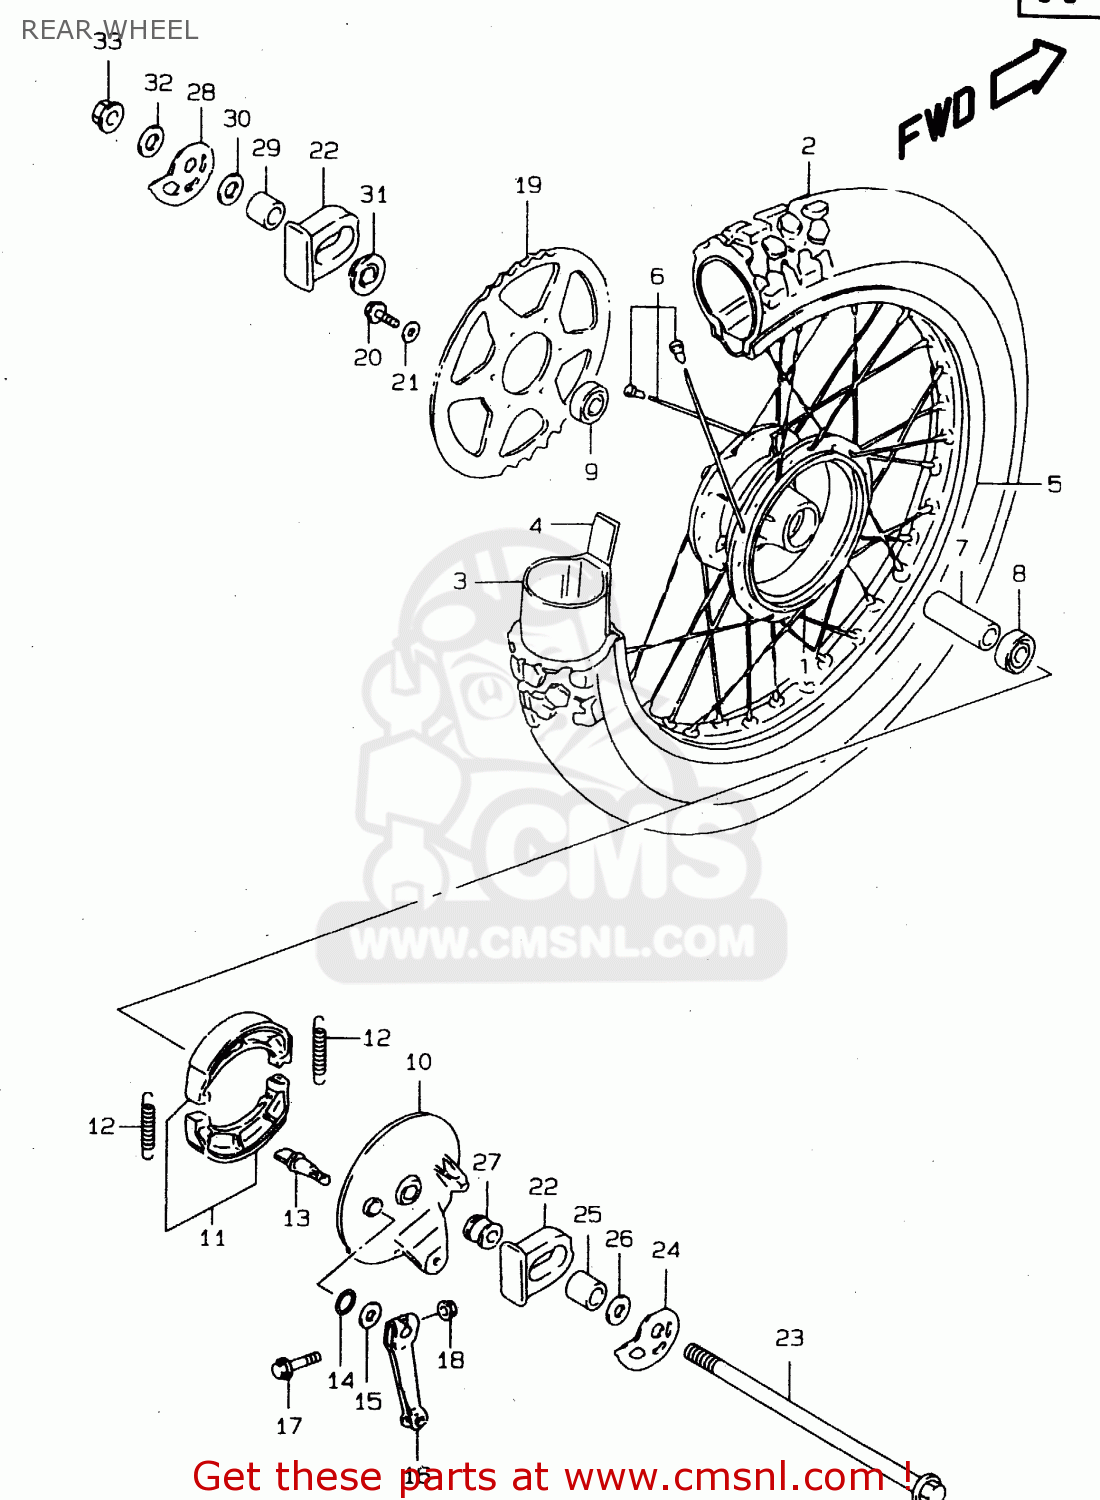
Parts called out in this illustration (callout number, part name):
1	HUB,RR WHEEL
2	TIRE,RR(90/90-18 51P)
3	TUBE ASSY,INNER
4	PROTECTOR,INNER TUBE
5	RIM,RR WHEEL(18X1.85 FE)
6	SPOKE SET,RR WHEEL
7	SPACER(15.3X21.7X107.5)
8	BEARING
9	BEARING
10	PANEL,RR BRAKE ANCHOR
11	SHOE SET,BRAKE (NAS)
12	SPRING(L:34)
13	CAM,BRAKE
14	O RING(D:2.5,ID:13.8)
15	WASHER(14.5X22X1.6)
16	LEVER,RR BRAKE CAM
17	BOLT
18	NUT
19	SPROCKET,RR(NT:53)
20	BOLT(8X30)
21	WASHER
22	CAP,RR SWINGING ARM
23	AXLE,RR
24	ADJUSTER,CHAIN,R
25	SPACER,CHAIN ADJUSTER
26	WASHER(15.5X26X2.3)
27	SPACER,RR AXLE,R
28	ADJUSTER,CHAIN,L
29	SPACER,CHAIN ADJUSTER
30	WASHER(15.5X26X2.3)
31	SPACER,RR AXLE,L
32	WASHER
33	NUT
